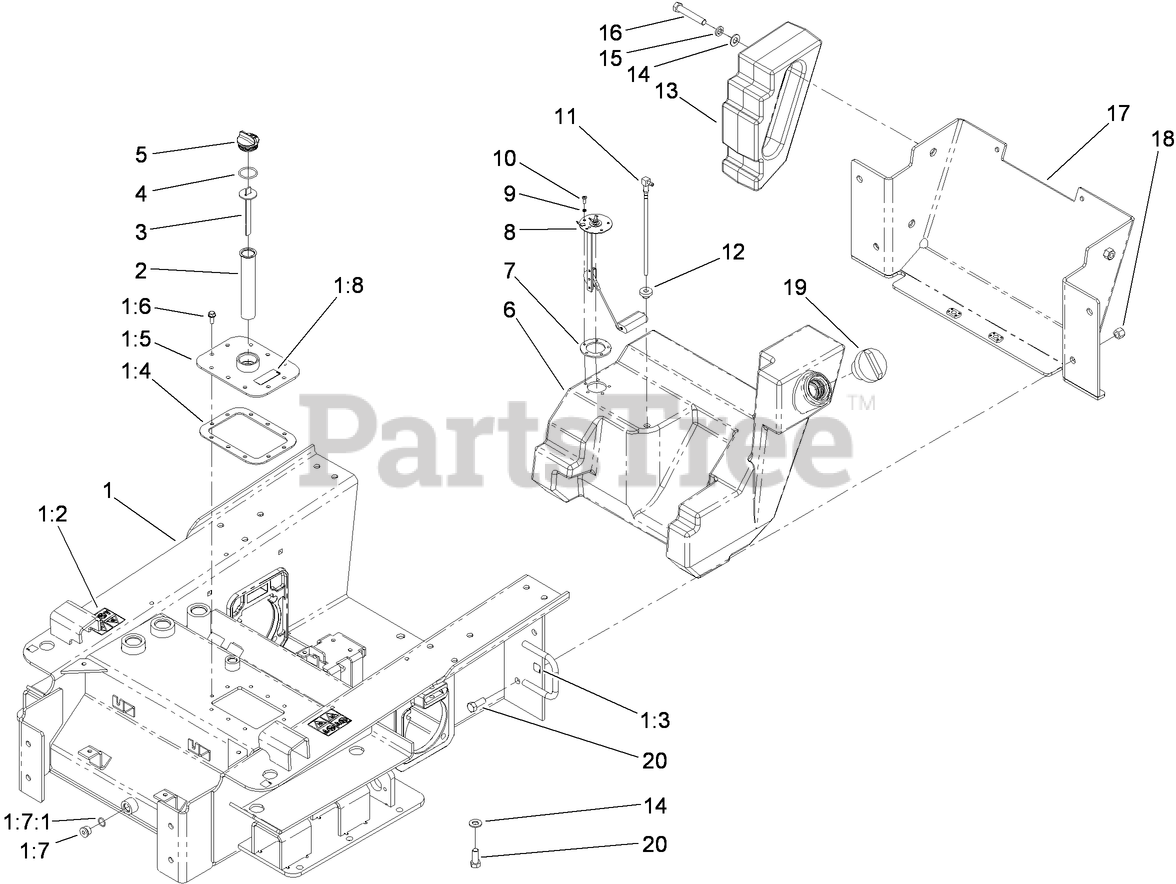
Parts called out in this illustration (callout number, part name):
1	CHASSIS ASM
1:2	DECAL-WARNING
1:3	DECAL-POINT, LIFT
1:4	GASKET-COVER, ACCESS
1:5	TANK COVER ASM
1:6	SCREW
1:7	PLUG-HEX
1:7:1	O-RING
1:8	DECAL-OIL, HYD
2	FILTER-SCREEN
3	DIPSTICK-OIL
4	O-RING
5	PLUG-PLASTIC
6	TANK-FUEL
7	GASKET-SENDER, FUEL
8	SENDER-FUEL
9	WASHER-LOCK
10	SCREW-PPH
11	PIPE-STAND
12	BUSHING
13	COUNTERWEIGHT-REAR
14	WASHER-FLAT
15	WASHER-LOCK
16	SCREW-HH
17	COVER-REAR
18	NUT-LOCK, NI
19	CAP-FUEL
20	SCREW-HH
